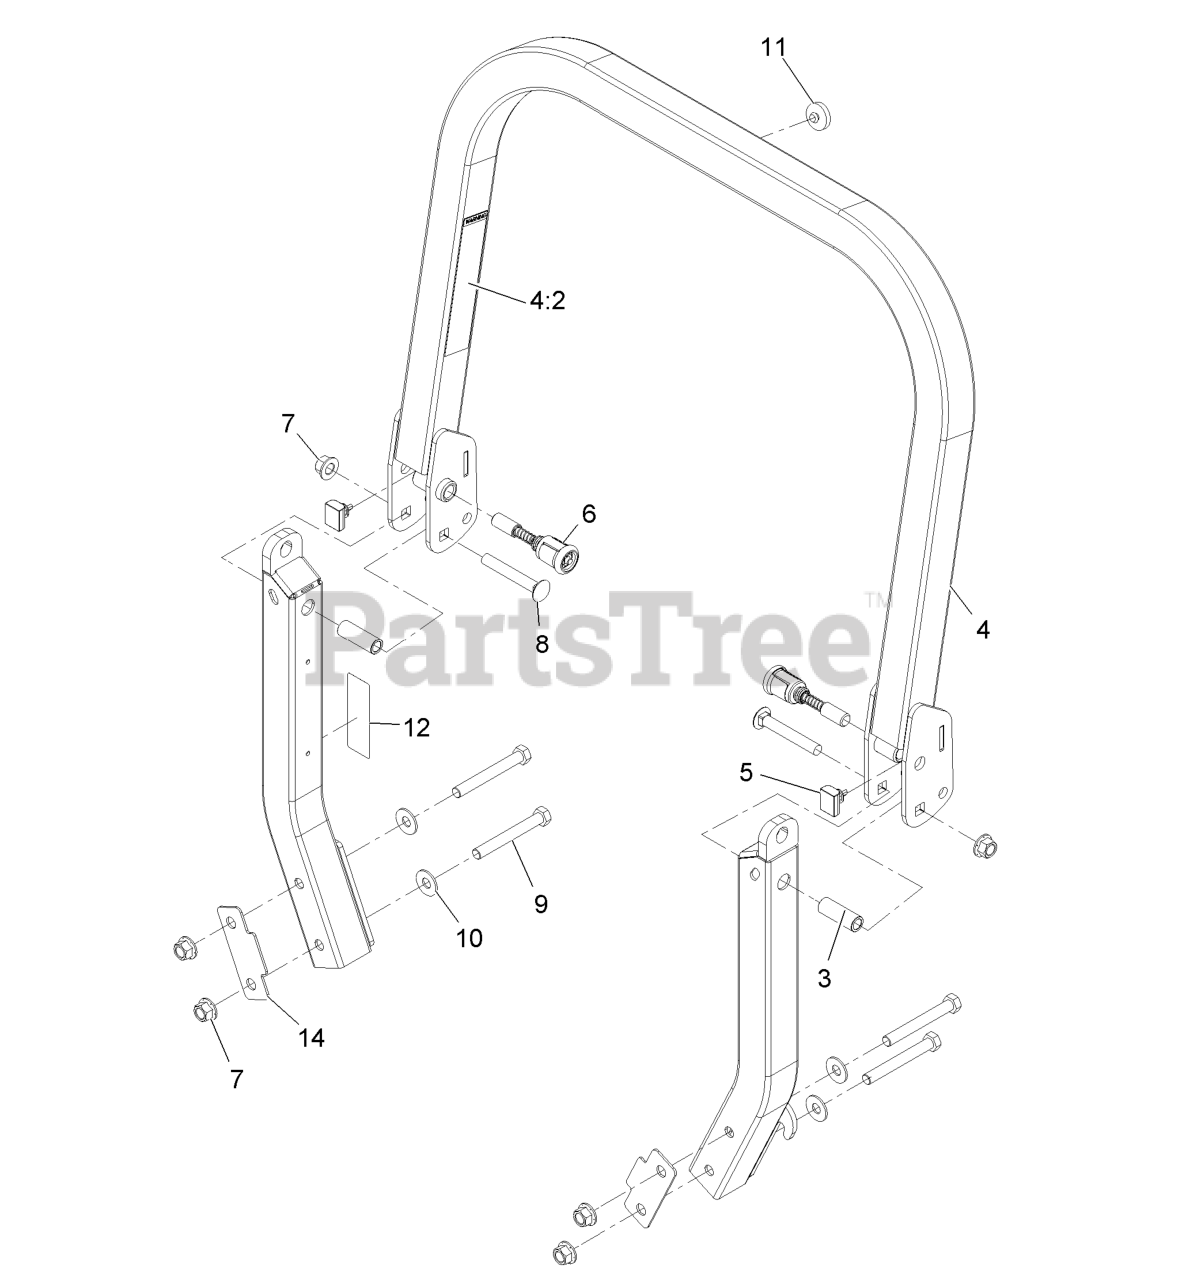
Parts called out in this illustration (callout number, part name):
4	UPPER ROPS ASM
4:2	DECAL-WARNING, FOLDING RO
5	BUMPER-ROPS
6	PIN-SPRING
7	Nut-Lock 1/2-13
8	SCREW-CARR
9	SCREW-HH
10	WASHER-SPRING
11	BUMPER-PUSH-IN, RUBBER
12	DECAL-CAUTION
